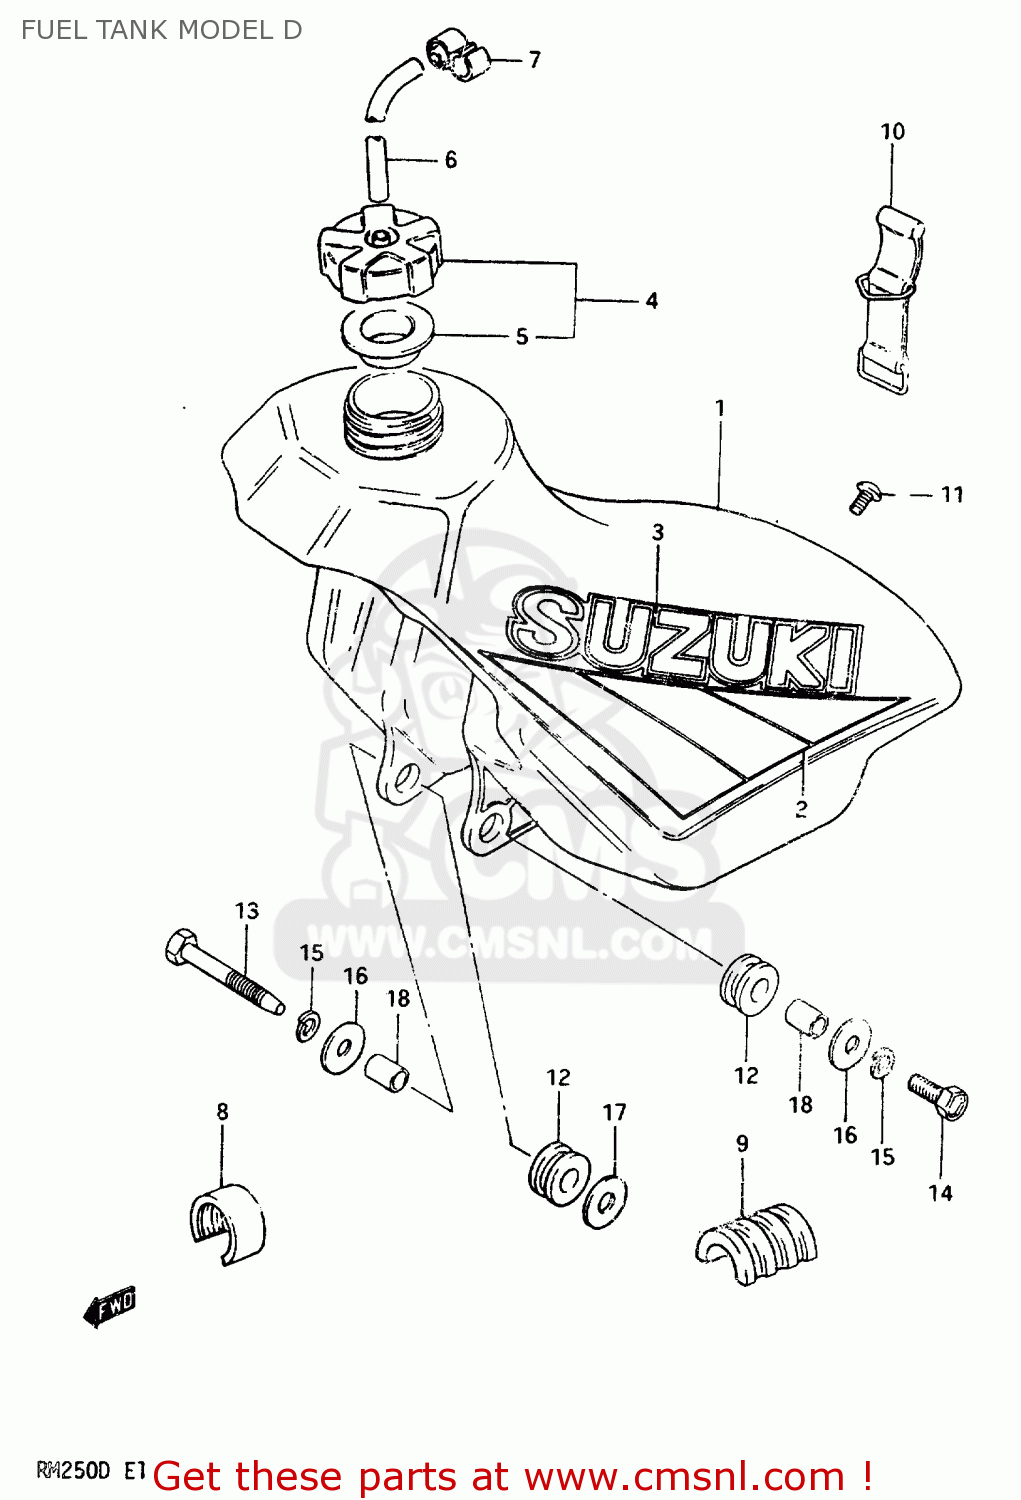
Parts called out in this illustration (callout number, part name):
1	TANK ASSEMBLY,FUEL
2	TAPE SET,FUEL TANK
3	EMBLEM
4	CAP SET,FUEL TANK
5	GASKET,FUEL TANK CAP (NAS)
6	HOSE
7	CLAMP,BREATHER HOSE
8	CUSHION,FUEL TANK UPR FR
9	CUSHION,FUEL TANK,UPPER
10	BAND
11	SCREW (6X15)
12	CUSHION
13	BOLT,8X75
14	BOLT
15	LOCK WASHER
16	WASHER
17	WASHER(8.5X26X1.2)
18	SPACER (8.8X12X13.5)
